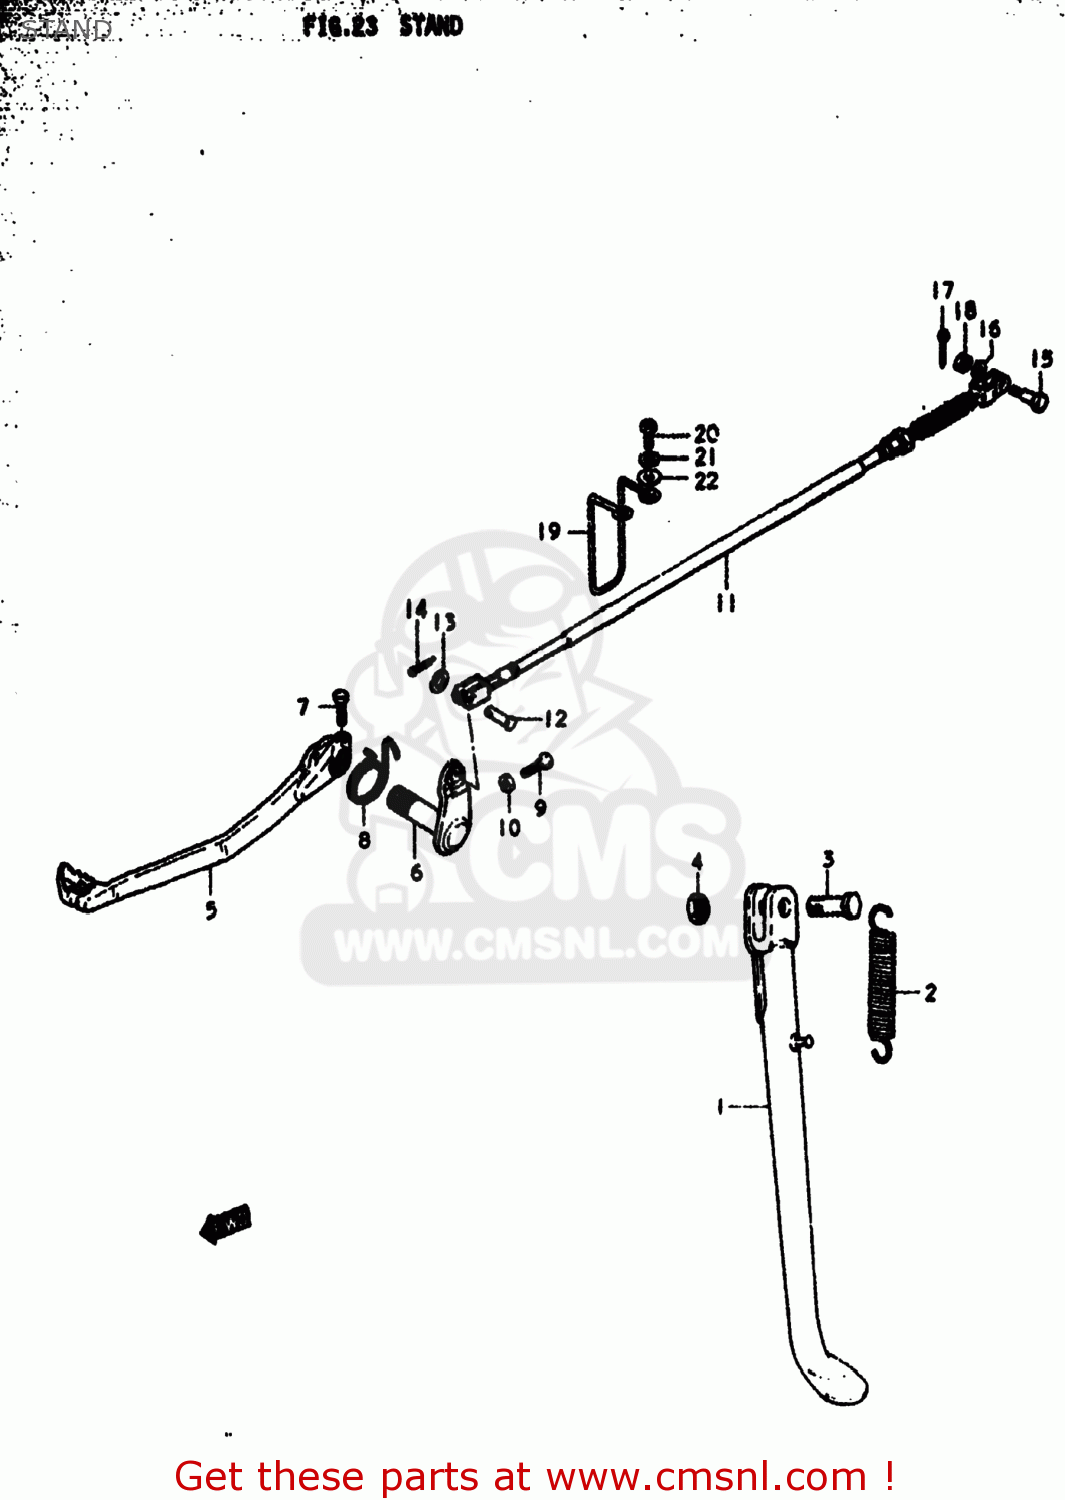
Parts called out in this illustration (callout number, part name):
1	STAND,SIDE
2	SPRING
3	BOLT(10X30)
4	NUT
5	PEDAL,BRAKE
6	ARM,BRAKE PEDAL
7	BOLT
8	SPRING
9	BOLT(6X23)
10	NUT
11	CABLE,RR BRAKE
12	PIN(L:17.5)
13	WASHER
14	PIN
15	BOLT
16	SHIM (8.5X16,5X0.8)
17	PIN
18	NUT
19	GUIDE,BRAKE CABLE
20	BOLT
21	LOCK WASHER
22	WASHER
